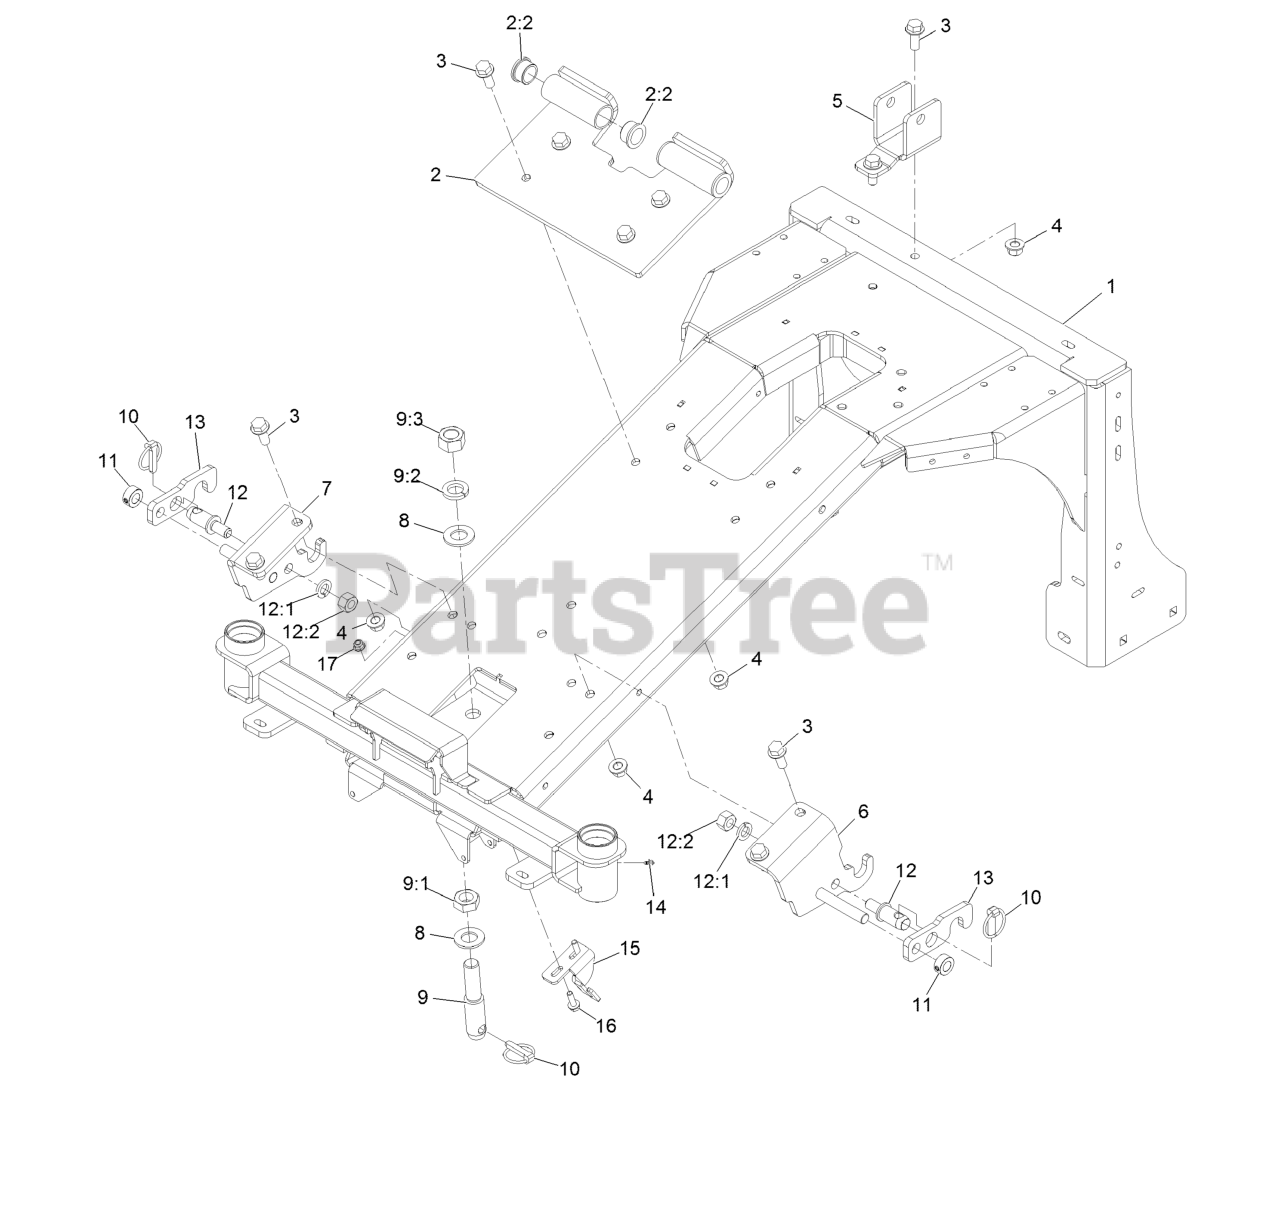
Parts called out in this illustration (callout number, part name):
1	FRONT FRAME ASM
2	PIVOT-ARM, LIFT ASM
2:2	BUSHING-FLANGE
3	SCREW-HHF
4	Nut-Lock 1/2-13
5	BRACKET-MOUNT, CYLINDER
6	X-REF 135-9471-05
7	HITCH PIN-RH
8	WASHER-FLAT
9	1-1/8 X 5-1/4 LIFT ARM PI
9:1	NUT-JAM
9:2	WASHER-LOCK/SP
9:3	NUT-HEX
10	PIN-LYNCH
11	5/8 SHAFT COLLAR
12	7/8 X 3-1/8 ANCHOR PIN (2
12:1	WASHER-LOCK
12:2	NUT-HEX
13	PLATE-ATTACHMENT, LOCK
14	FITTING-GREASE, ZERK
15	BRACKET-CABLE, LCS
16	SCREW-HH
17	NUT-HF, NI
